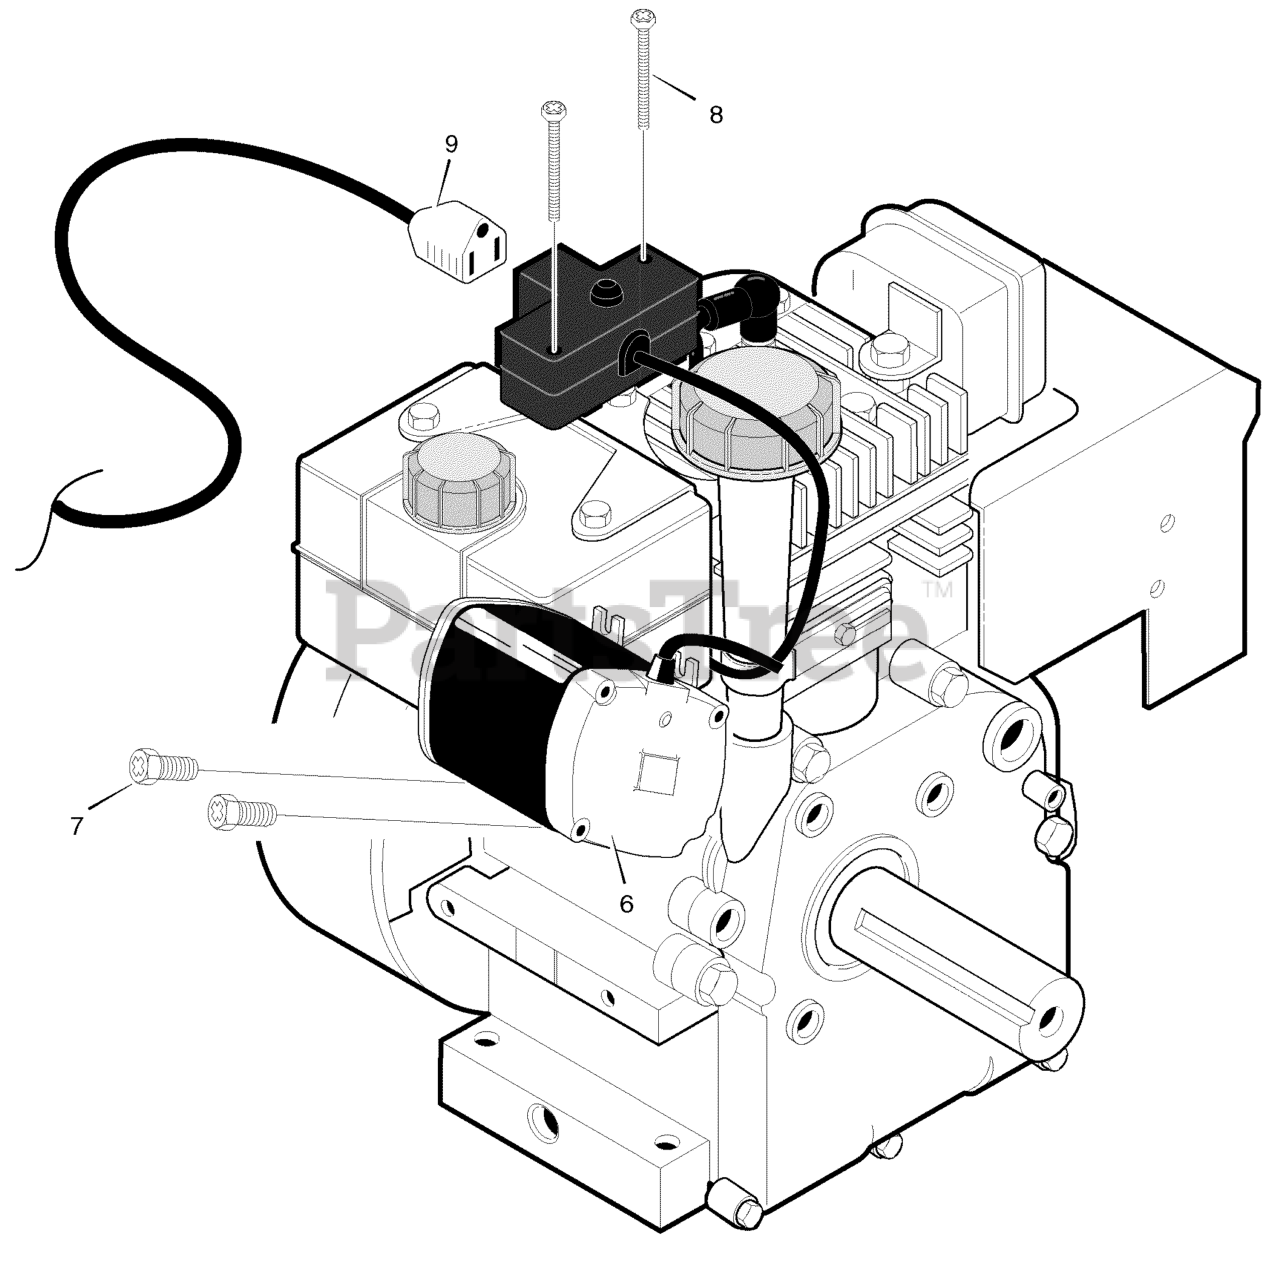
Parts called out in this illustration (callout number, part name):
6	MOTOR, STARTER
8	SCREW
9	CORD, STARTER
